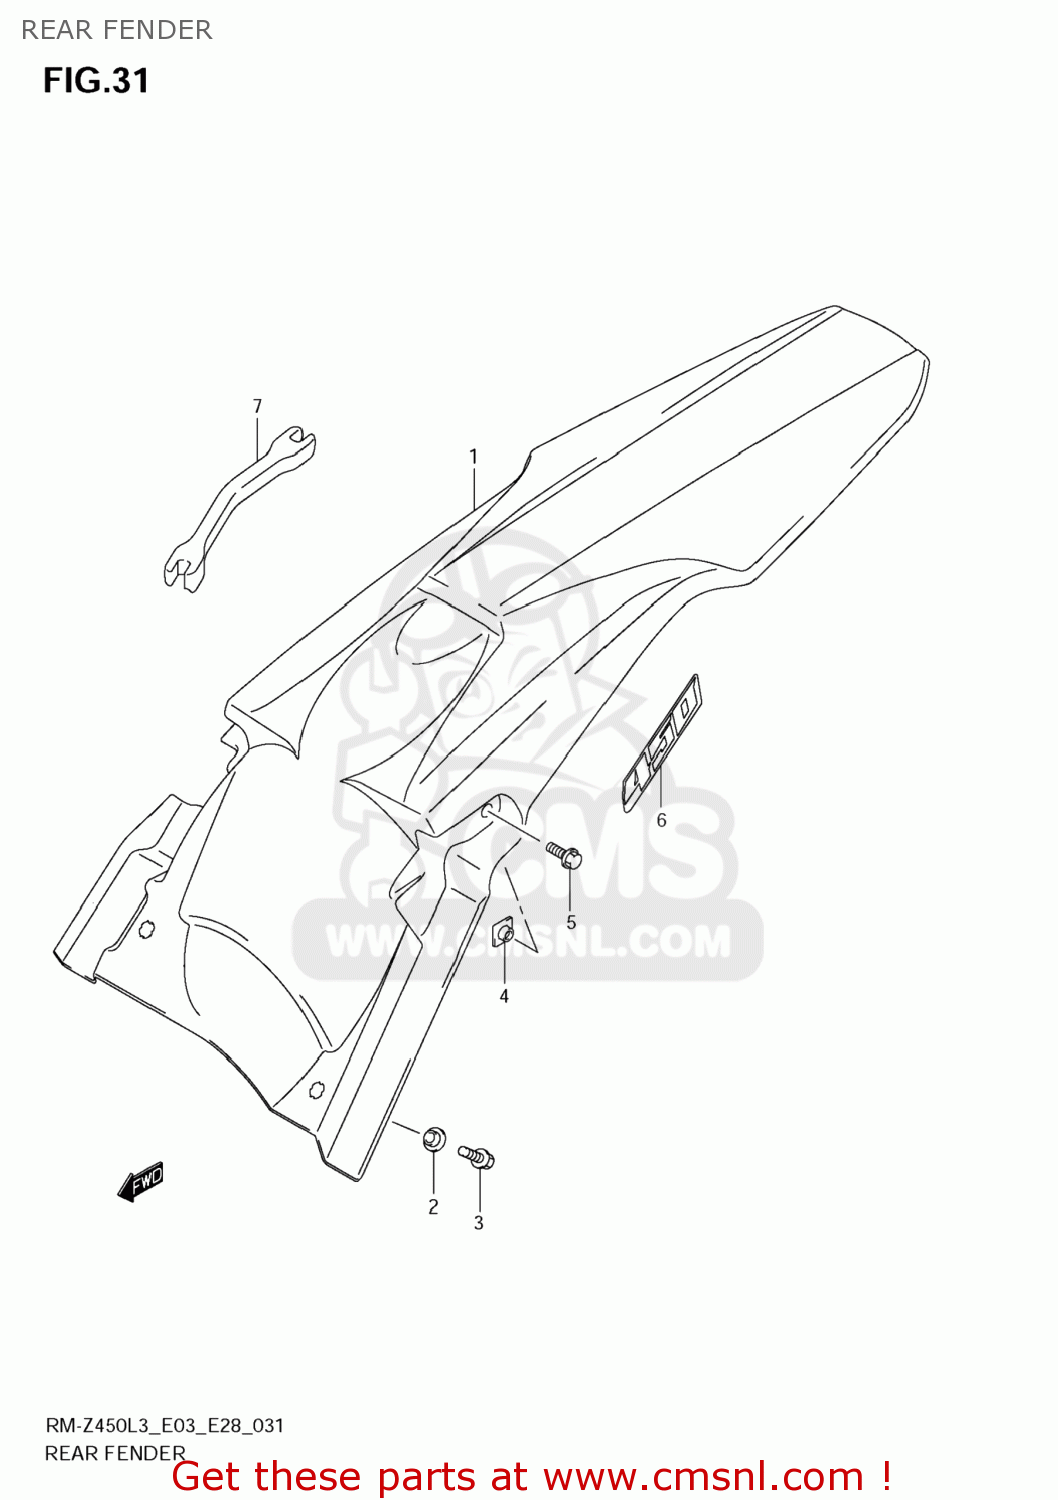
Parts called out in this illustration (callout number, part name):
1	FENDER,RR
2	WASHER,FR FENDER
3	BOLT
4	NUT,RR REFLECTOR
5	BOLT
6	EMBLEM,RR FENDER
7	OPEN SPANNER(6.4X6.8)
